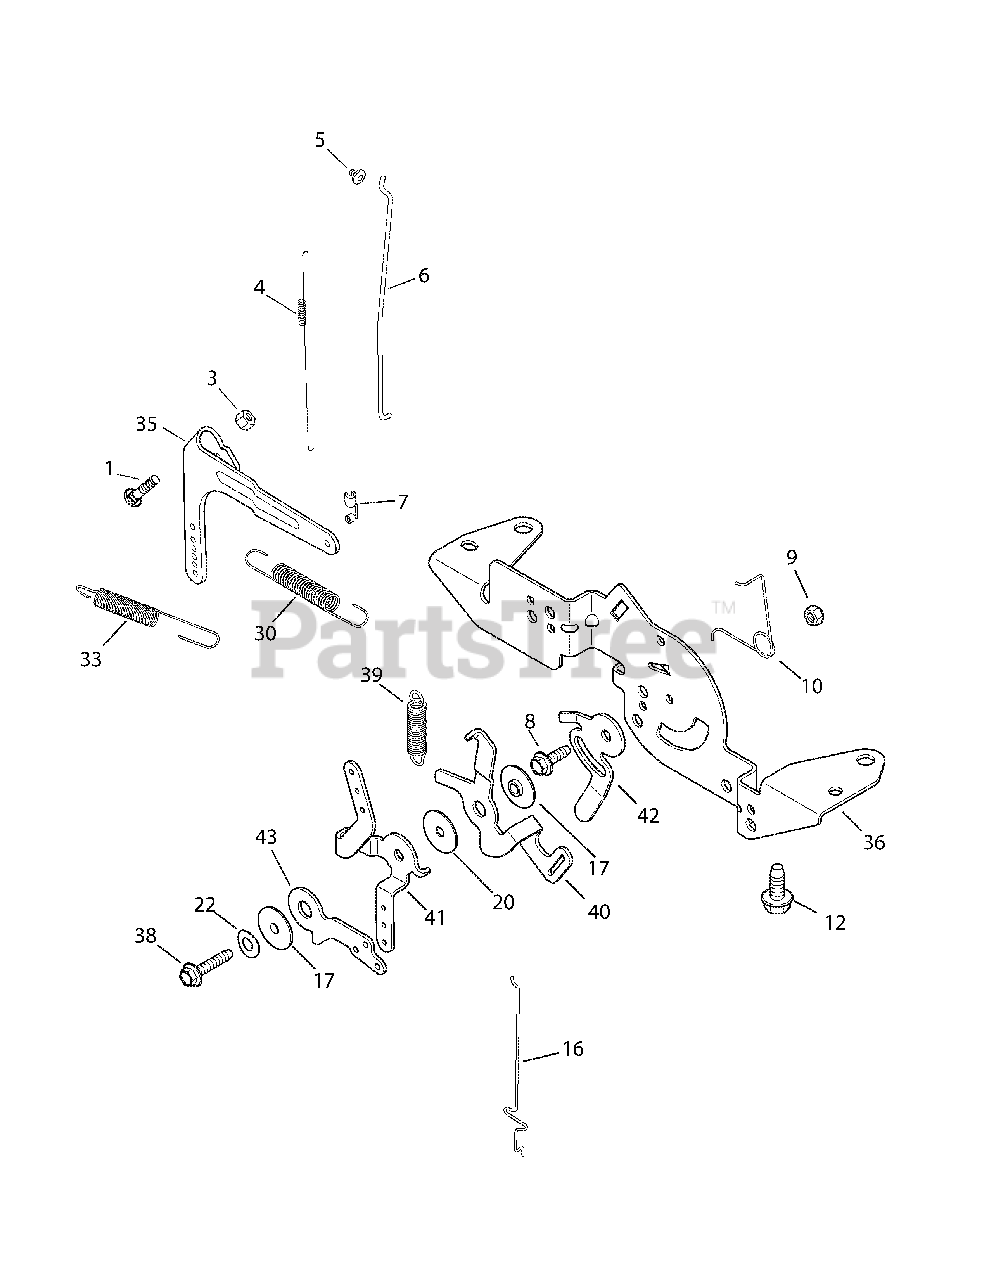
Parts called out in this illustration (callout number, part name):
1	Rd. Hd. Sq. Neck Bolt, M6 X 1.0 X 25
3	Flg. Nut, M6 X 1.0
4	Linkage Spring
5	Linkage Retaining Bushing
6	Throttle Linkage
7	Throttle Linkage Bushing
8	Flg. Thd. Frm. Screw, M5 X 0.8 X 16
9	Lock Nut, M5 X .8
10	Choke Return Spring
12	Flg. Thd. Frm. Screw, M6 X 1.0 X 16
14	Cable Clamp
15	Lbd. Thd. Frm. Screw, M5 X 0.8 X 16
16	Choke Linkage
17	Control Assembly Spacer
20	Flat Washer. 5.5mm
22	Spring Washer, 1/4
30	Governor Spring
33	Governor Spring
35	Governor Lever
36	Control Bracket
38	Thd. Frm. Screw, M5 X 0.8 X 25mm
39	Speed Control Spring
40	Governor Spring Lever
41	Speed Control Lever
42	Speed Setting Lever
